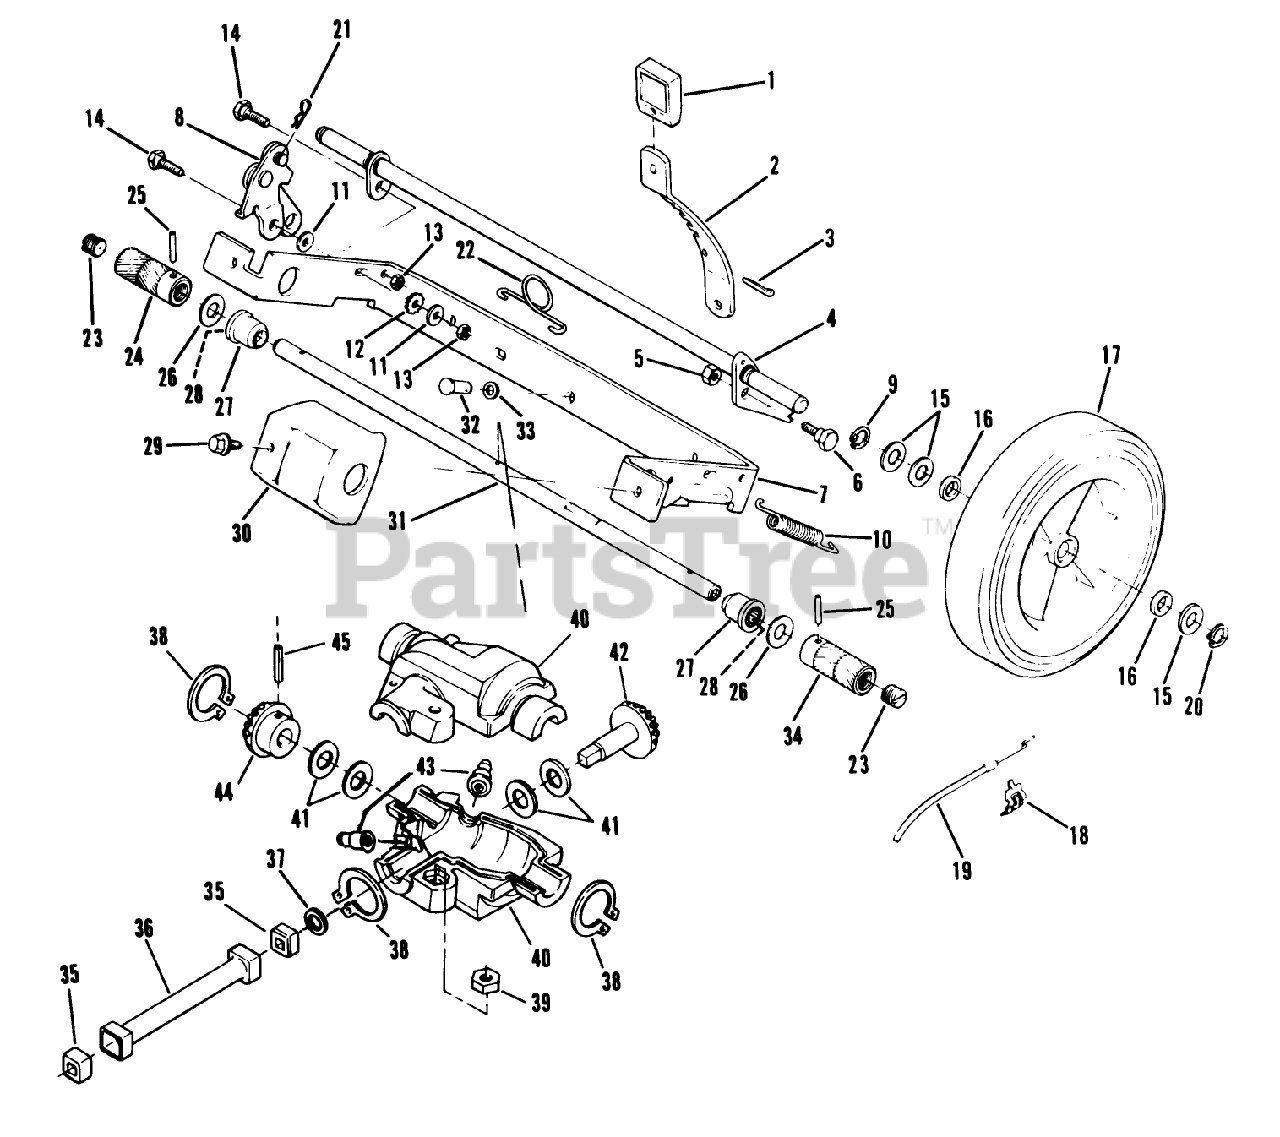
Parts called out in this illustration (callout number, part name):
1	KNOB
2	LEVER
5	LOCKNUT E
6	BOLT RB&W
7	BRK-21" AXLE
9	RET RING
10	SPRING
11	WASHER S
13	STOP NUT
14	BOLT RB&W
15	SPACER
16	WASHER
20	RET RING
22	SPRING N.A.S
23	GREASE PLUG
25	PIN
28	BEARING AY F
30	GUARD
31	DRIVE SHFT TAG AY
32	PIN
33	WASHER SPRING LAR
35	BUSHING
37	O-RING
39	LOCKNUT E
41	THRUST WASHER
43	ZERK FITTING
45	ROLL PIN
